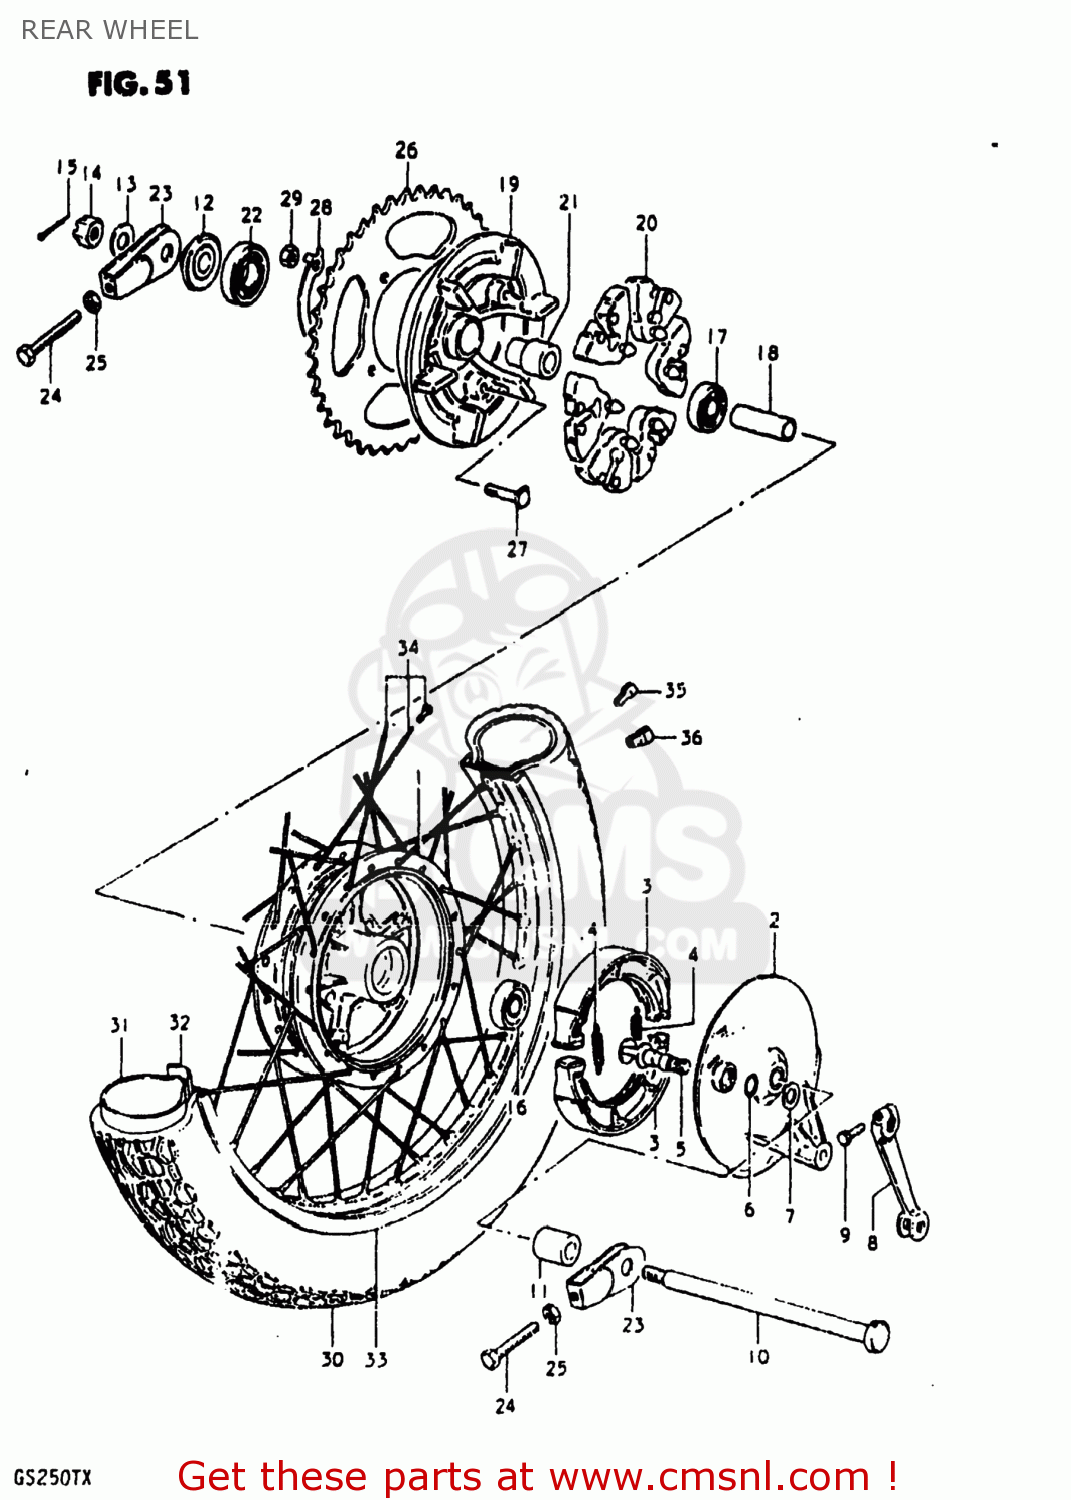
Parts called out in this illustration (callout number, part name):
1	HUB,RR
2	PANEL,REAR HUB
3	SHOE,BRAKE
4	SPRING,BRAKE SHOE
5	CAM,FRONT BRAKE
6	O-RING,BOSS
7	WASHER (15X24X1.6)
8	LEVER,RR BRAKE CAM
9	BOLT
10	AXLE,REAR
11	SPACER
12	SPACER,REAR AXLE,LEFT
13	WASHER
14	NUT
15	COTTER PIN
16	BEARING, RH
17	BEARING
18	SPACER(15.3X21.7X58)
19	DRUM,REAR SPROCKET MOUNT
20	ABSORBER,RR HUB SHOCK
21	RETAINER,RR SPROCKET MTG
22	BEARING
23	ADJUSTER,CHAIN,R
24	BOLT
25	NUT
26	SPROCKET,RR(NT:47)
27	BOLT(8X33.5)
28	WASHER,LOCK
29	NUT (8MM)
30	TIRE
31	TUBE 3.50-17 089-432MM
32	PROTECTOR,WHEEL,INNER
33	RIM,REAR WHEEL
34	SPOKE ASSY,RR
35	BALANCER,WHEEL (B)
36	BALANCER,WHEEL (30G)
